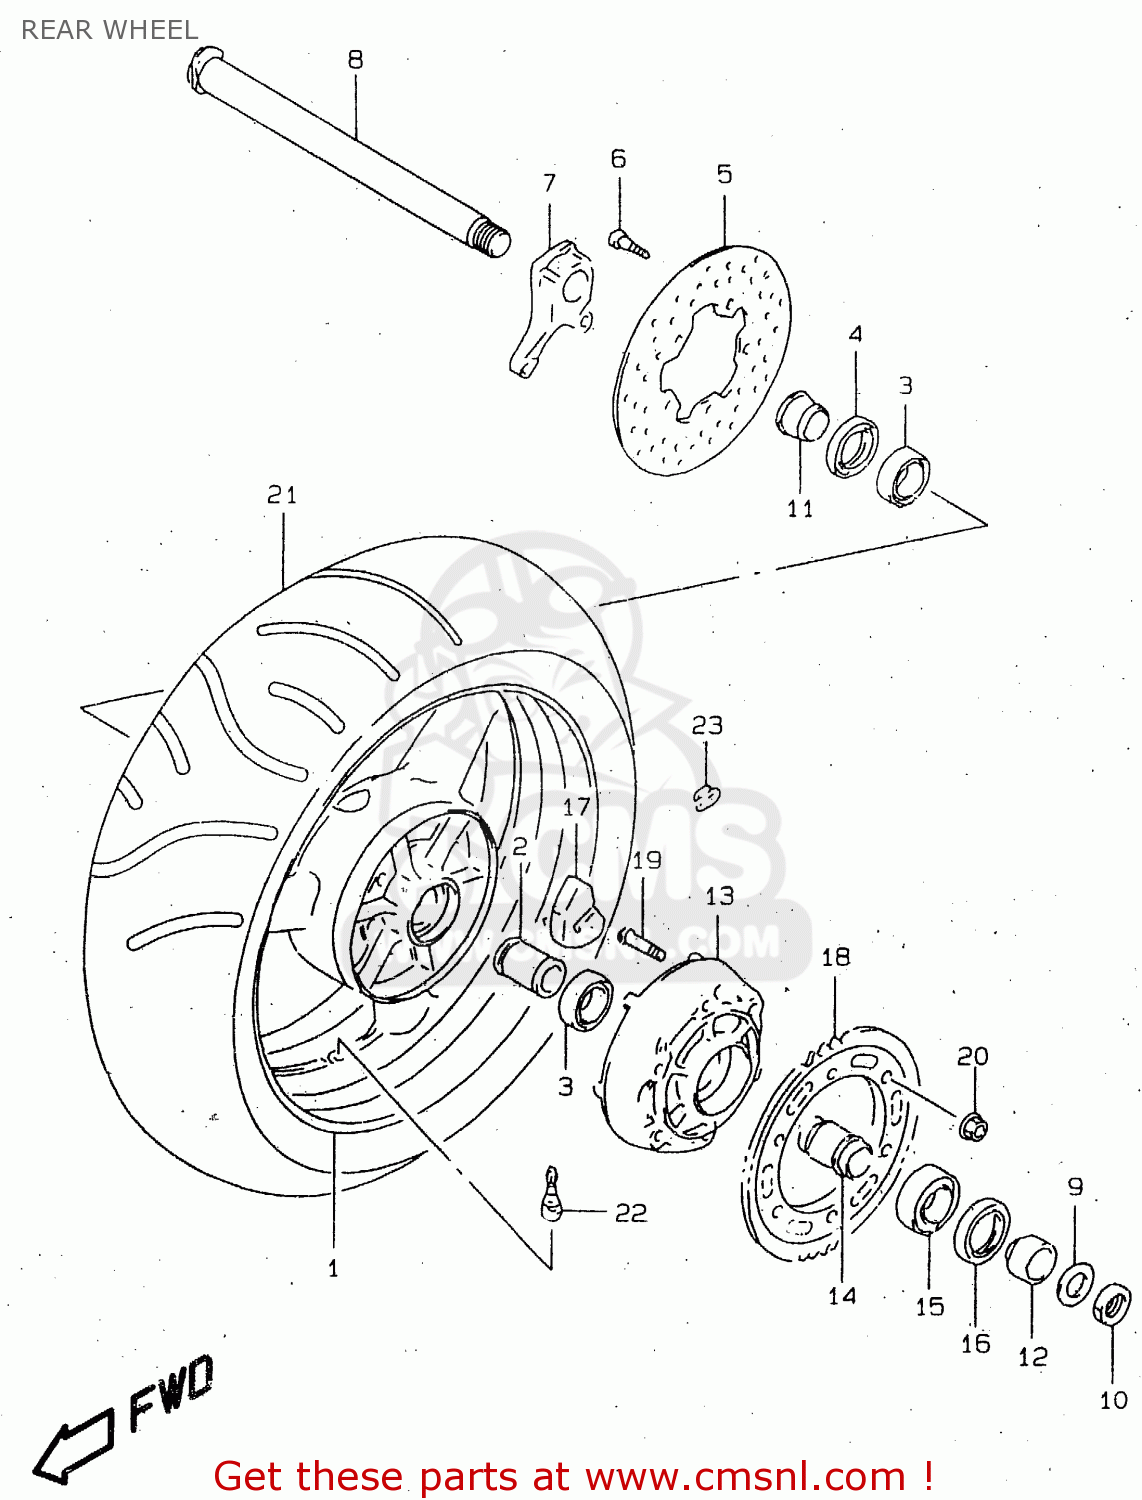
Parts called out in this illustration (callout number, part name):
1	WHEEL,REAR (17XMT6.00)
2	SPACER,RR HUB BEARING
3	BEARING(32X58X13)
4	SEAL,OIL(38X58X7)
5	DISC,RR BRAKE
6	BOLT 8X33
7	BRACKET,RR CALIPER
8	AXLE,RR
9	WASHER(25.2X42X3.2)
10	NUT
11	SPACER,RR AXLE,R
12	SPACER,RR AXLE,L
13	DRUM,RR SPROCKET
14	RETAINER,RR SPROCKET DRUM
15	BEARING
16	SEAL,OIL(39X65X7)
17	ABSORBER,RR HUB SHOCK
18	SPROCKET,RR(NT:39-530)
19	BOLT
20	NUT
21	TIRE 190/50 ZR17 (73W),M
22	VALVE ASSY,WHEEL RIM(TR412)
23	BALANCER,WHEEL (10G)
